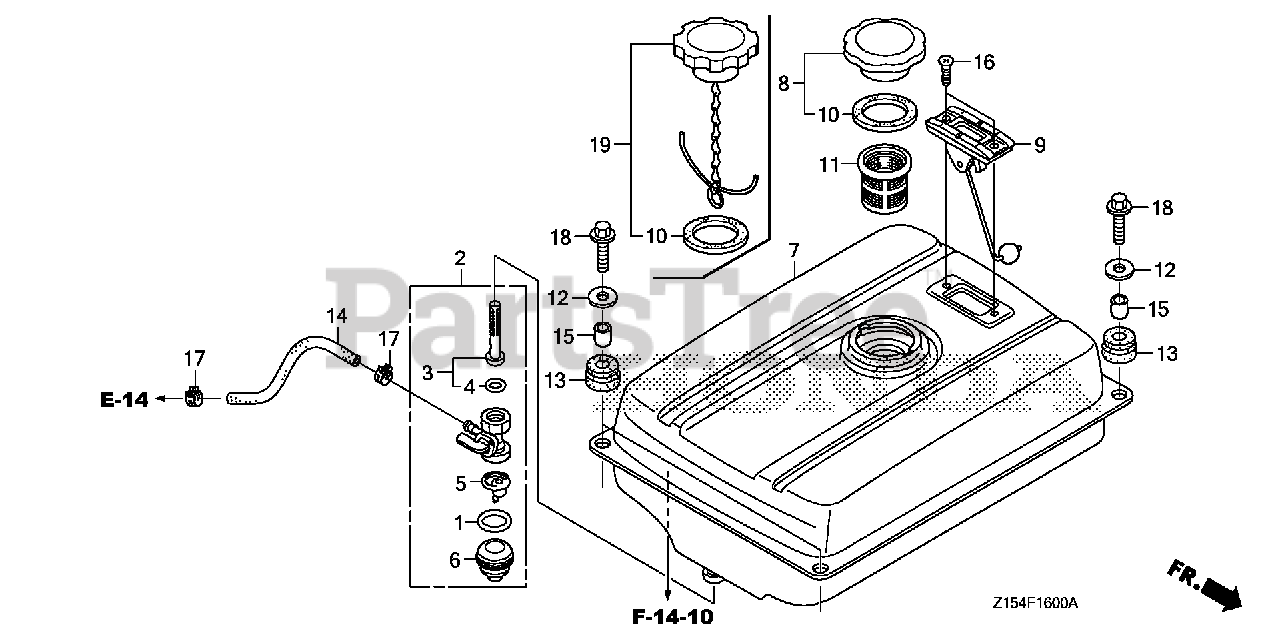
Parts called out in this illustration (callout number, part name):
1	GASKET, FUEL STRAINER CUP
2	PETCOCK ASSY.
3	SCREEN SET, FUEL STRAINER
4	O-RING (9.0X1.3)
5	FILTER, CUP
6	CUP, FUEL STRAINER
7	TANK, FUEL *R280* (POWER RED)
9	METER ASSY., FUEL
10	GASKET, FUEL FILLER CAP
11	FILTER, FUEL
12	WASHER (6MM)
13	RUBBER, TANK CUSHION
14	TUBE, FUEL (4.5X110) (FKM)
15	COLLAR, TANK CUSHION
16	SCREW, FLAT (5X10)
17	CLAMP, TUBE (D8)
18	BOLT, FLANGE (6X22)
19	CAP, FUEL FILLER
